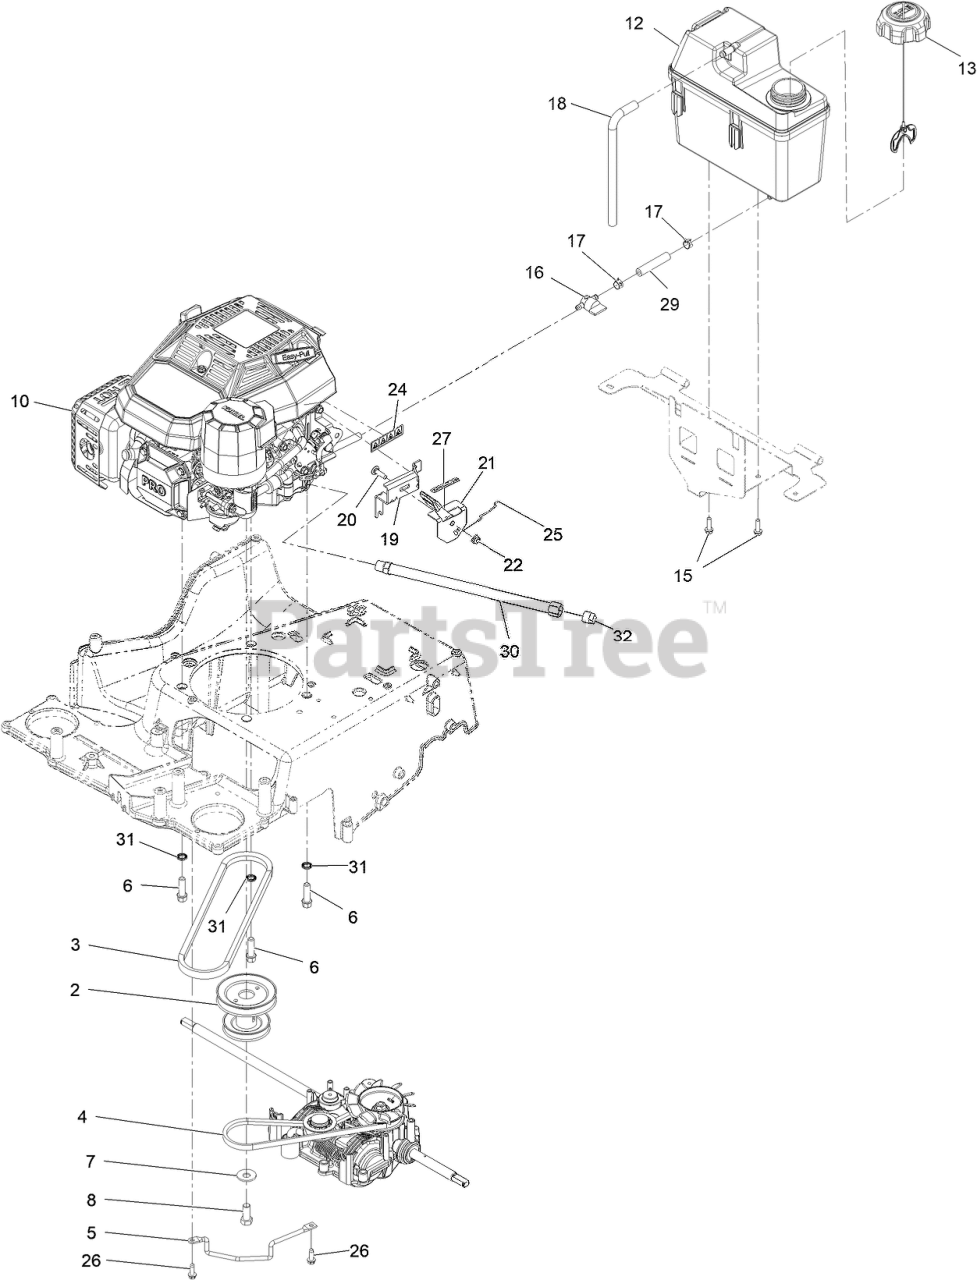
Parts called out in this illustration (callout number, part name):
2	Pulley-Engine
5	ROD-GUIDE, BELT
6	SCREW-TAPTITE
7	WASHER-BELLEVILLE
8	SCREW-HH
10	Engine-Kohler
12	TANK-FUEL
13	CAP-FUEL
15	SCREW-HWH
16	VALVE-FUEL
17	CLAMP-HOSE
18	HOSE-VENT, CANISTER
19	BRACKET-THROTTLE
20	SCREW-CARR
21	CONTROL-THROTTLE
24	DECAL-WARNING, ENGINE
25	Wire-Link
26	SCREW-HWHTF
27	DECAL-THROTTLE, CHOKE
29	HOSE-FUEL
30	HOSE-DRAIN, OIL
31	WASHER-LOCK
32	PLUG-PIPE, SQH
